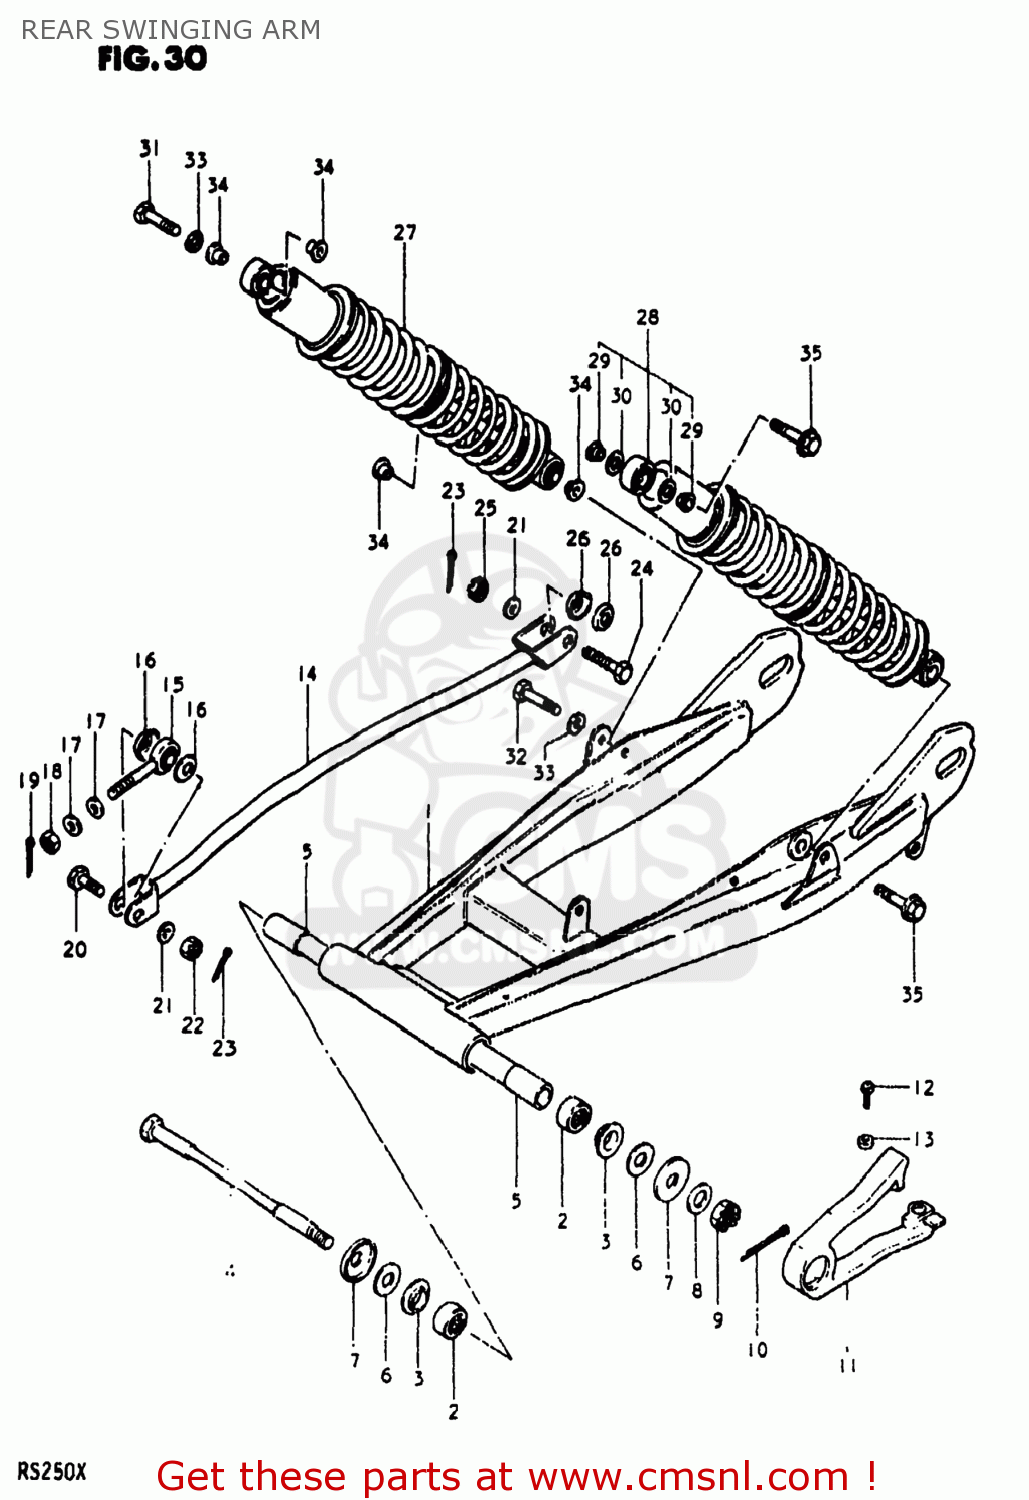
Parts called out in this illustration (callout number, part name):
1	SWING ARM ASSEMBLY,REAR
2	BEARING
3	BUSHING,REAR SWING ARM PIVOT
4	SHAFT,REAR SWING ARM
5	SPACER,REAR SWING ARM
6	WASHER
7	COVER,RR SWGARM DUST SEAL
8	WASHER
9	NUT 14MM
10	COTTER PIN
11	BUFFER,CHAIN TOUCH DEFLECTOR
12	SCREW,CHAIN TOUCH DEFEND
13	SPACER (5.5X8X4)
14	LINK,REAR TORQUE
15	BEARING
16	17
17	WASHER
18	NUT
19	PIN
20	BOLT 8X28
21	WASHER
22	NUT 8MM
23	PIN 20X20
24	BOLT 8X28
25	NUT 8MM
26	27-1
27	ABSORBER ASSEMBLY,REAR SHOCK
28	ABSORBER ASSEMBLY,REAR SHOCK
29	SPACER,REAR SHOCK ABSORBER
30	DUST SEAL,REAR SHOCK
31	BOLT
32	BOLT
33	WASHER
34	SPACER,RR SHK ABS INNER
35	BOLT 10X40
